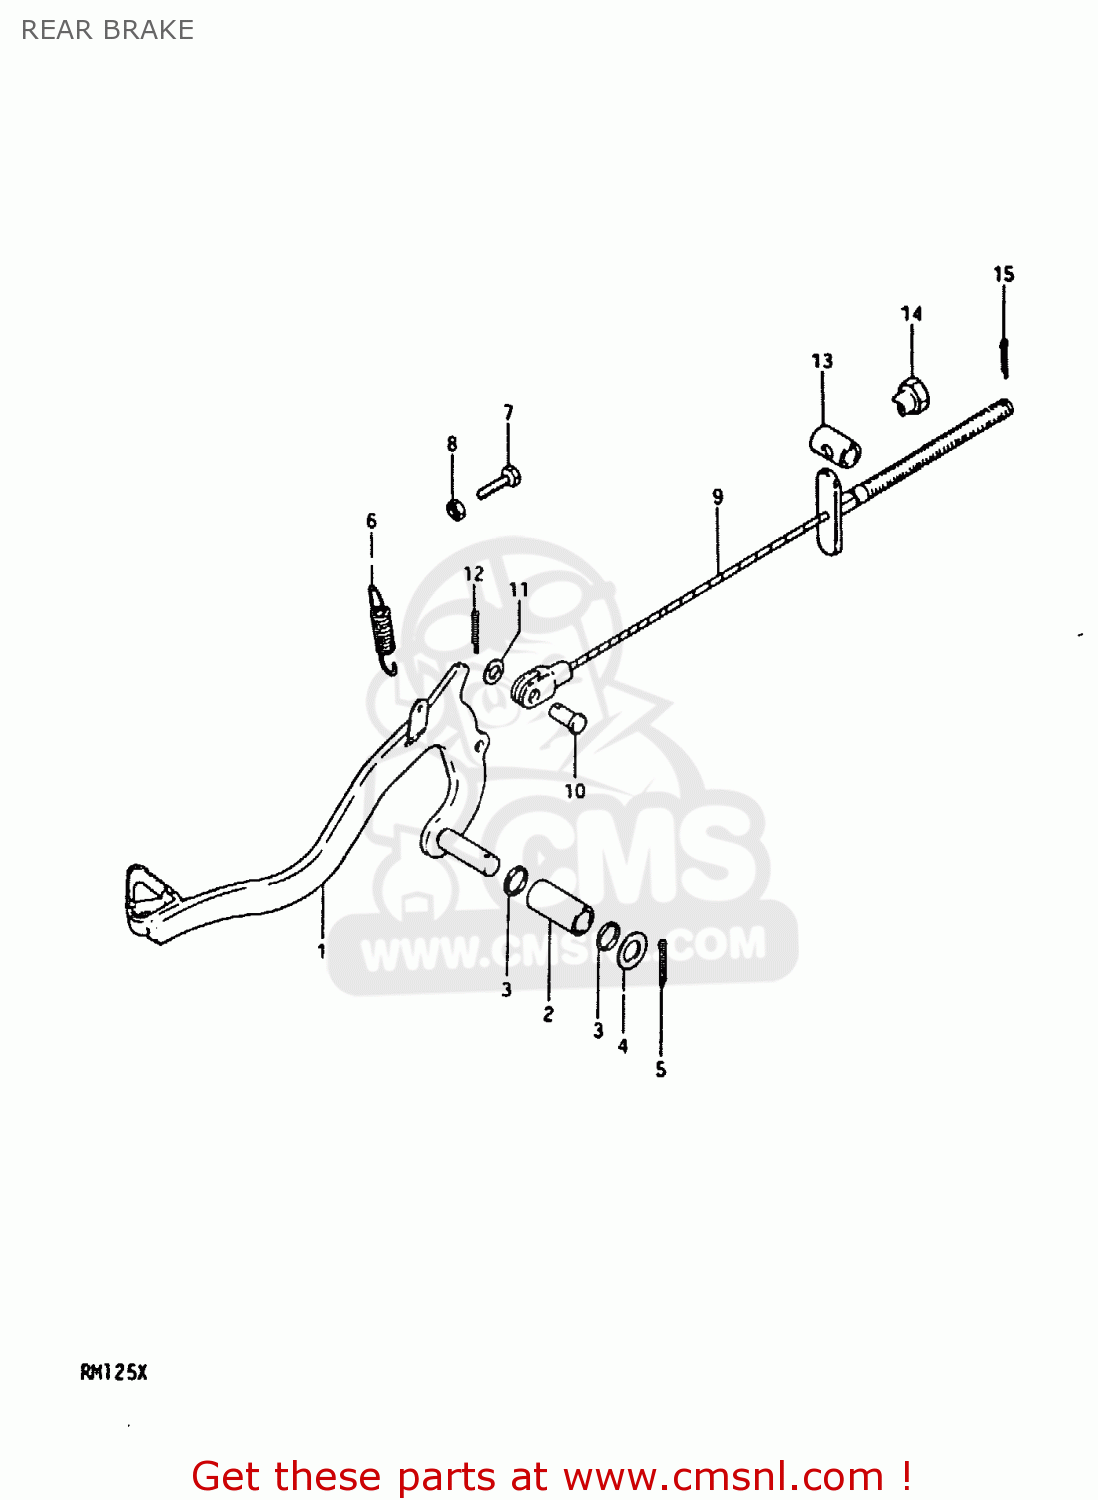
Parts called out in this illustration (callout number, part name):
1	PEDAL,BRAKE
2	BUSHING
3	O RING(D:2.2,ID:11.8)
4	WASHER
5	PIN 30X20
6	SPRING
7	BOLT(6X23)
8	NUT
9	CABLE ASSEMBLY,REAR BRAKE
10	PIN(L:17.5)
11	WASHER
12	PIN 20X20
13	PIN
14	NUT
15	PIN
